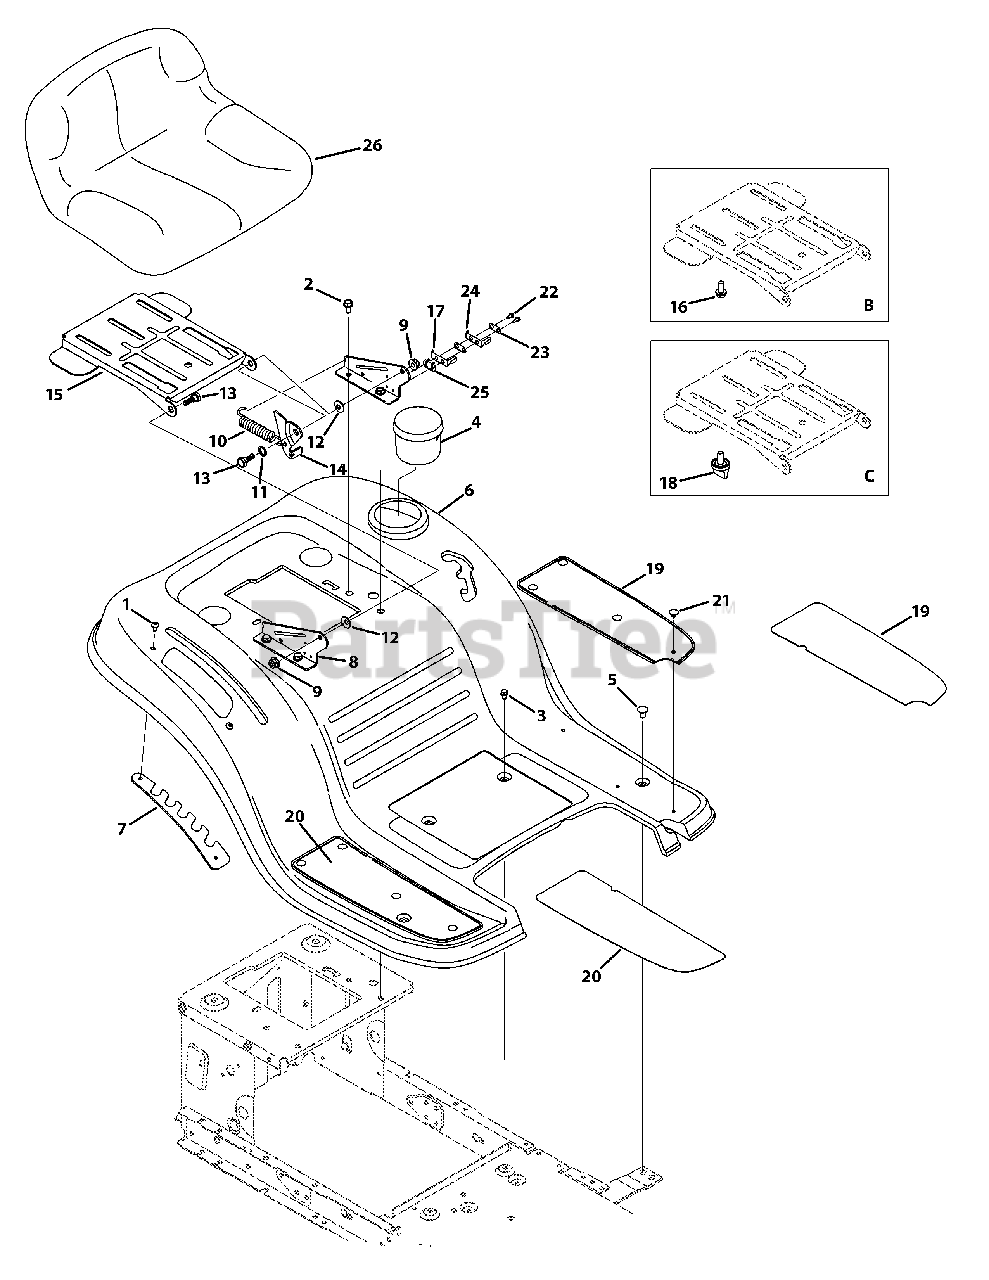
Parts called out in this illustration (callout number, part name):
1	Screw, 1/4-20 x .500
2	Screw, 5/16-18 x .750
3	Screw Pan Torx Head, 1/4-20 x .500
5	Screw Carriage, 1/4-20 x .62
7	Lift Adjuster Bracket - Powder Black
8	Seat Mount Bracket - Powder Black
9	Flangelock Nut, 5/16-18
10	Extension Springing
11	Flat Washerer, .510x .750 x .033
12	Bell Washerer, .340 x .872 x .060
13	Shoulder Screw, 5/16-18 x .437 x .268
14	Lift Seat Bracket
15	Pivot Seat Manual Adjust Bracket
16	Hex Head Flange, 3/8-16 x .875
17	Inner Seat Springing
18	Knob, 3/8-16 x .875
19	Foot Pad, LH
19	Foot Pad, Abrasive, LH
20	Foot Pad, RH
20	Foot Pad, Abrasive, RH
21	Ratchet Clip, .250 x .500
22	Screw, 8-18 x .500
23	Insulator Plate
24	Outer Seat Springing
25	Insulator Boss Plate
26	Med Back Seat, Black, Set-up B or C
